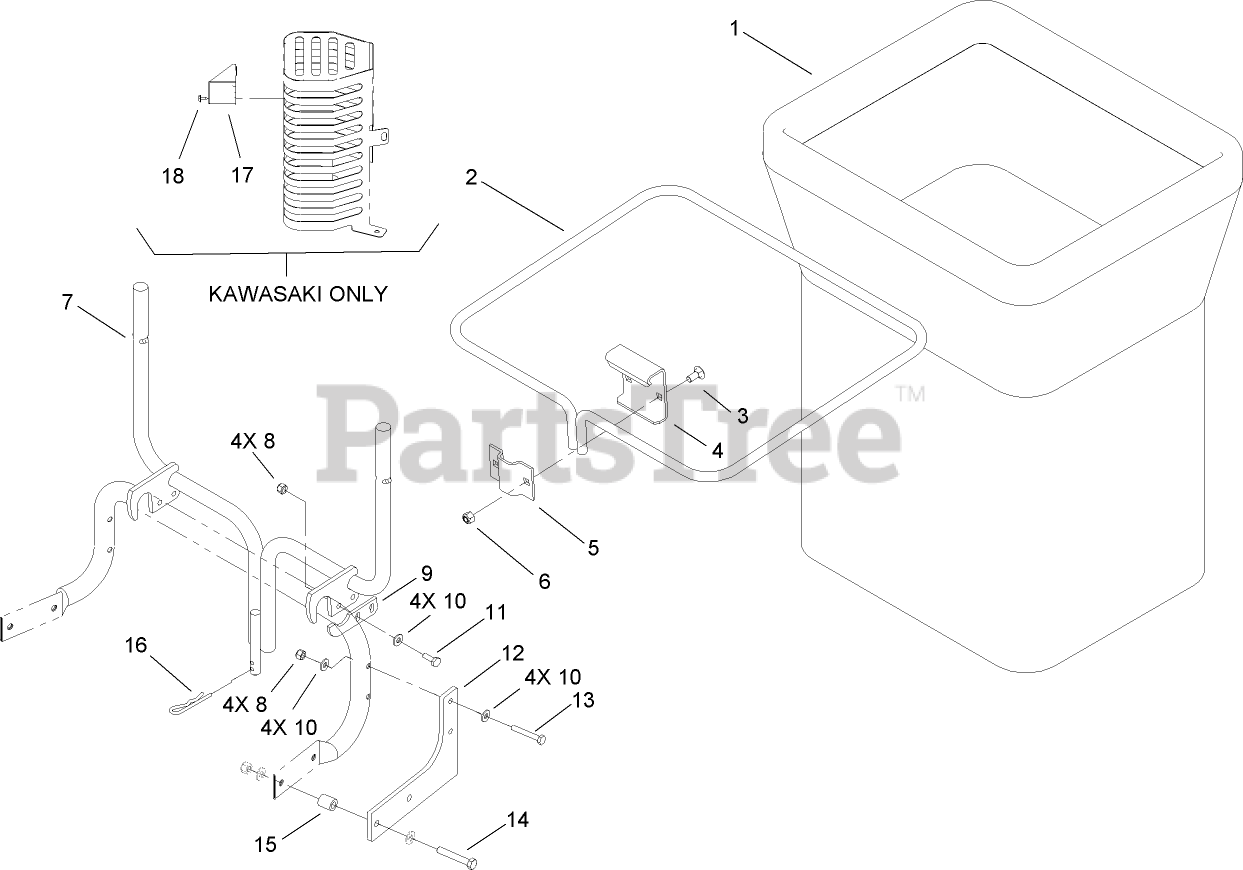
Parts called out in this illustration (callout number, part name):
1	BAG-DEPTH
2	FRAME-BAG
3	BOLT-CARR
4	HANGER-BAG
6	NUT-LOCK, NI
7	BAGGER BRACKET ASM
8	NUT-LOCK, NI
9	PLATE-BAGGER
10	WASHER-FLAT
11	SCREW-HH
12	GUSSET-BAGGER
13	SCREW-HH
14	SCREW-HH
15	SPACER
16	PIN-COTTER, HAIR
17	DEFLECTOR
18	SCREW-HWHTF
